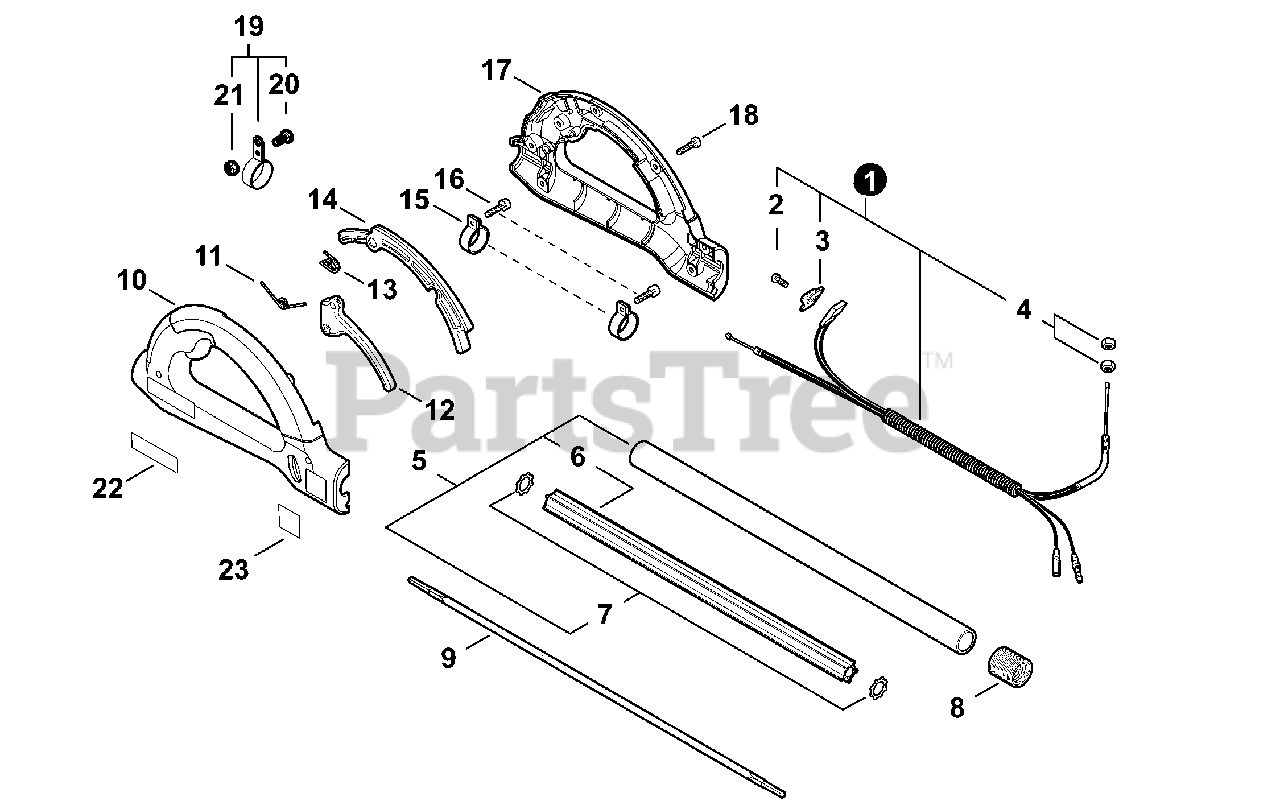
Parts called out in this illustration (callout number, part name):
1	CABLE ASSY, CONTROL
2	SCREW 3×10
3	KNOB, SWITCH - ORANGE
5	PIPE, MAIN
8	TUBE, FLEXIBLE
9	DRIVESHAFT - FLEXIBLE
10	BODY, HANDLE - LEFT
11	SPRING, TORSION
12	TRIGGER, THROTTLE
13	SPRING, TORSION
14	LOCKOUT, THROTTLE
16	BOLT, TORX 5×16
17	BODY, HANDLE - RIGHT
18	BOLT, TORX 5×16
19	HANGER KIT
20	BOLT, TORX 5×10
21	NUT, M5×8 NYLON INSERT
22	LABEL, ECHO
23	LABEL, CAUTION
